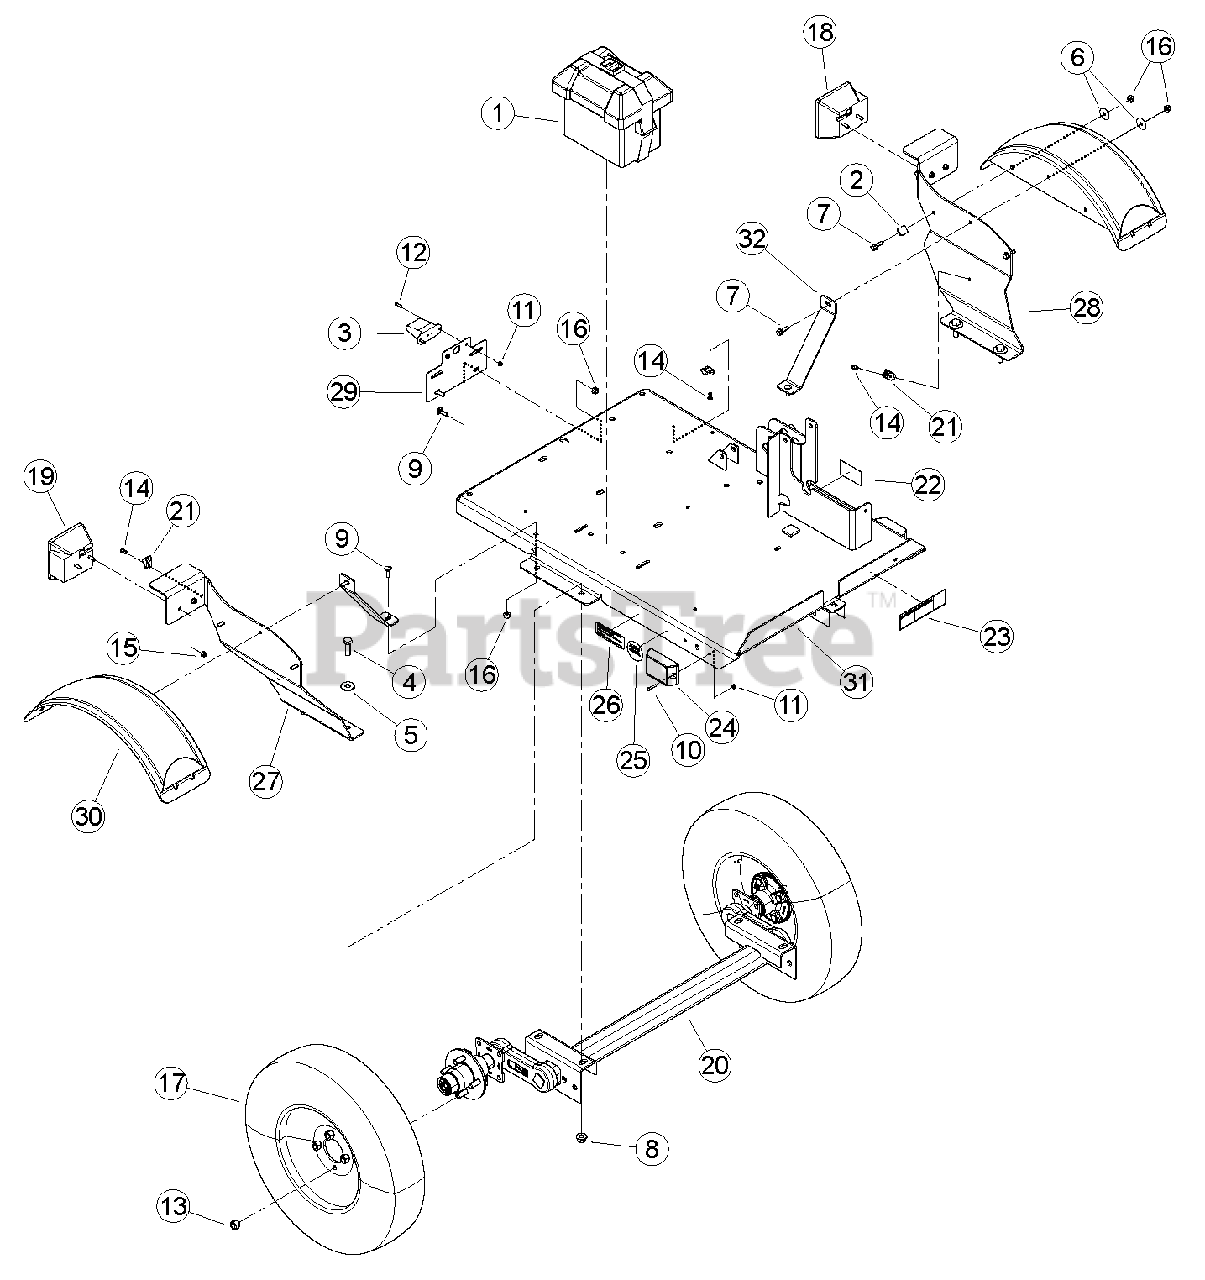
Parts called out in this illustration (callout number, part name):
1	BOX, SMALL BATTERY
2	CLAMP, 9/16 COATED
3	LIGHT, LICENSE PLATE
4	BOLT, 1/2 X 1-1/2 HEX HD GR5 ZP
5	WASHER, 1/2" FLAT ZP
6	WASHER, 5/16" FENDER ZP
7	BOLT, 5/16 X 1 FLANGE NC
8	NUT, 1/2-13 NYLOCK FLANGE
9	BOLT, 5/16 X 1" GR5 CRG ZP
10	SCREW, 10-24 X 1" RND HD PHL ZP MCH
11	NUT, 10/24 NYLOCK TYPE NM ZP
12	SCREW, #10-24 X 3/4" PAN HD PH ZP MCH
13	NUT, 1/2-20 WHEEL
14	RIVET, AL BLIND 1/4 X 3/4 DOME HEAD
15	NUT, 1/4-20 NYLOCK-FLANGE
16	NUT, 5/16-18 NYLOCK-FLANGE
17	ASSEMBLY, 5.30-12 TIRE + SPOKE RIM
18	LIGHT, LH TAIL
19	LIGHT, RH TAIL
20	AXLE, 1000LB TORSION
21	CLAMP, CABLE MOUNT
22	DECAL, 5.30-12 LOAD RATING (REPLACED AND SUPERSEDED PN 32161-00. FOR SERVICE ORDER PN 32156-00)
23	DECAL, CHECK WHEELS
24	LIGHT, AMBER MARKER
25	DECAL, NATM COMPLIANCE
26	DECAL, EPA EVAP
27	BRACKET, RH FENDER
28	BRACKET, LH FENDER
29	PLATE, LICENSE
30	FENDER, BLACK PLASTIC DRILLED
31	WELDMENT, CHIPPER TRAILER
32	BRACKET, FENDER
